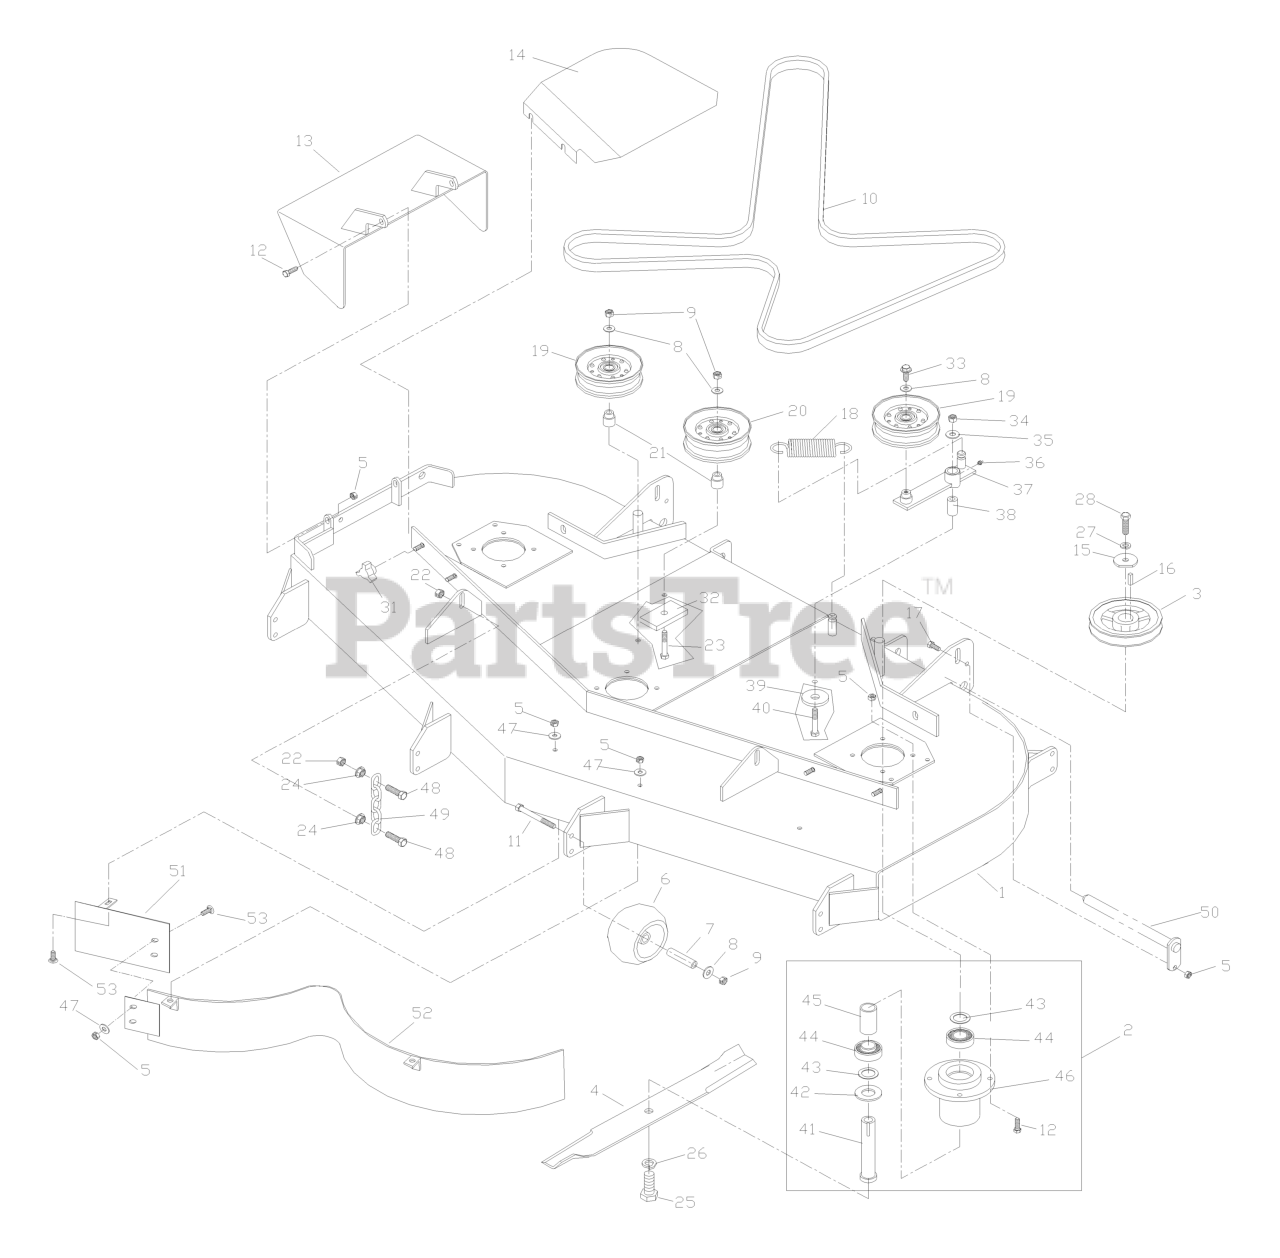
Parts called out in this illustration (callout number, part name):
1	DECK W/DECALS 61" HUS
2	HOUSING ASM.
4	BLADE OEM 21" (61" DECK)
5	NUT 5/16C CENTERLOCK
6	ANTI-SCALP ROLLER
8	WASHER 3/8 FLAT
9	NUT 3/8C CENTERBLOCK
10	DECK BELT 61
11	HCS 3/8C X 3 1/2
12	HCS 5/16C X 1
13	DISCHARGE CHUTE
14	61 B.S.PAINTED, RT
14	61 B.S.PAINTED, LT ORANGE
15	SPINDLE WASHER
16	KEY 1/4 SQ X 1 1/8
17	HCS 5/16C X 3/4
18	DECK SPRING
19	IDLER PULLEY
20	IDLER PULLEY (TALL)
21	IDLER BUSHING
22	NUT 7/16C CENTERLOCK
23	HCS 3/8C X 2 1/2
24	NUT 7/16C WHIZ
25	HCS 5/8F X 1 1/4
26	LOCKWASHER 5/8
27	WASHER 7/16 LOCK
28	HCS 7/16F X 1 1/2
31	KNOB, THREE PRONG
32	SUPPORT PLATE
33	4CS 3/8C X 1 SERRATED HEAD
34	NUT 1/2-13 HEX NYLOC ZD
35	WASHER 1/2 FLAT
36	ZERK
38	PIVOT BUSHING
39	WASHER, SUPPORT
40	HCS 1/2C X 3 1/4
42	MACHINERY BUSHING 10 GA.
43	BUSHING.MACHINE.18.GAUGE
44	BEARING
46	HOUSING, DIE CAST
47	WASHER 5/16 FLAT
48	HCS 7/16C X 1 1/2
49	LIFT CHAIN
51	CENTER BAFFLE - 61
52	MAIN BAFFLE - 61" BLK
53	CARRIAGE BOLT 5/16C X 5/8"
